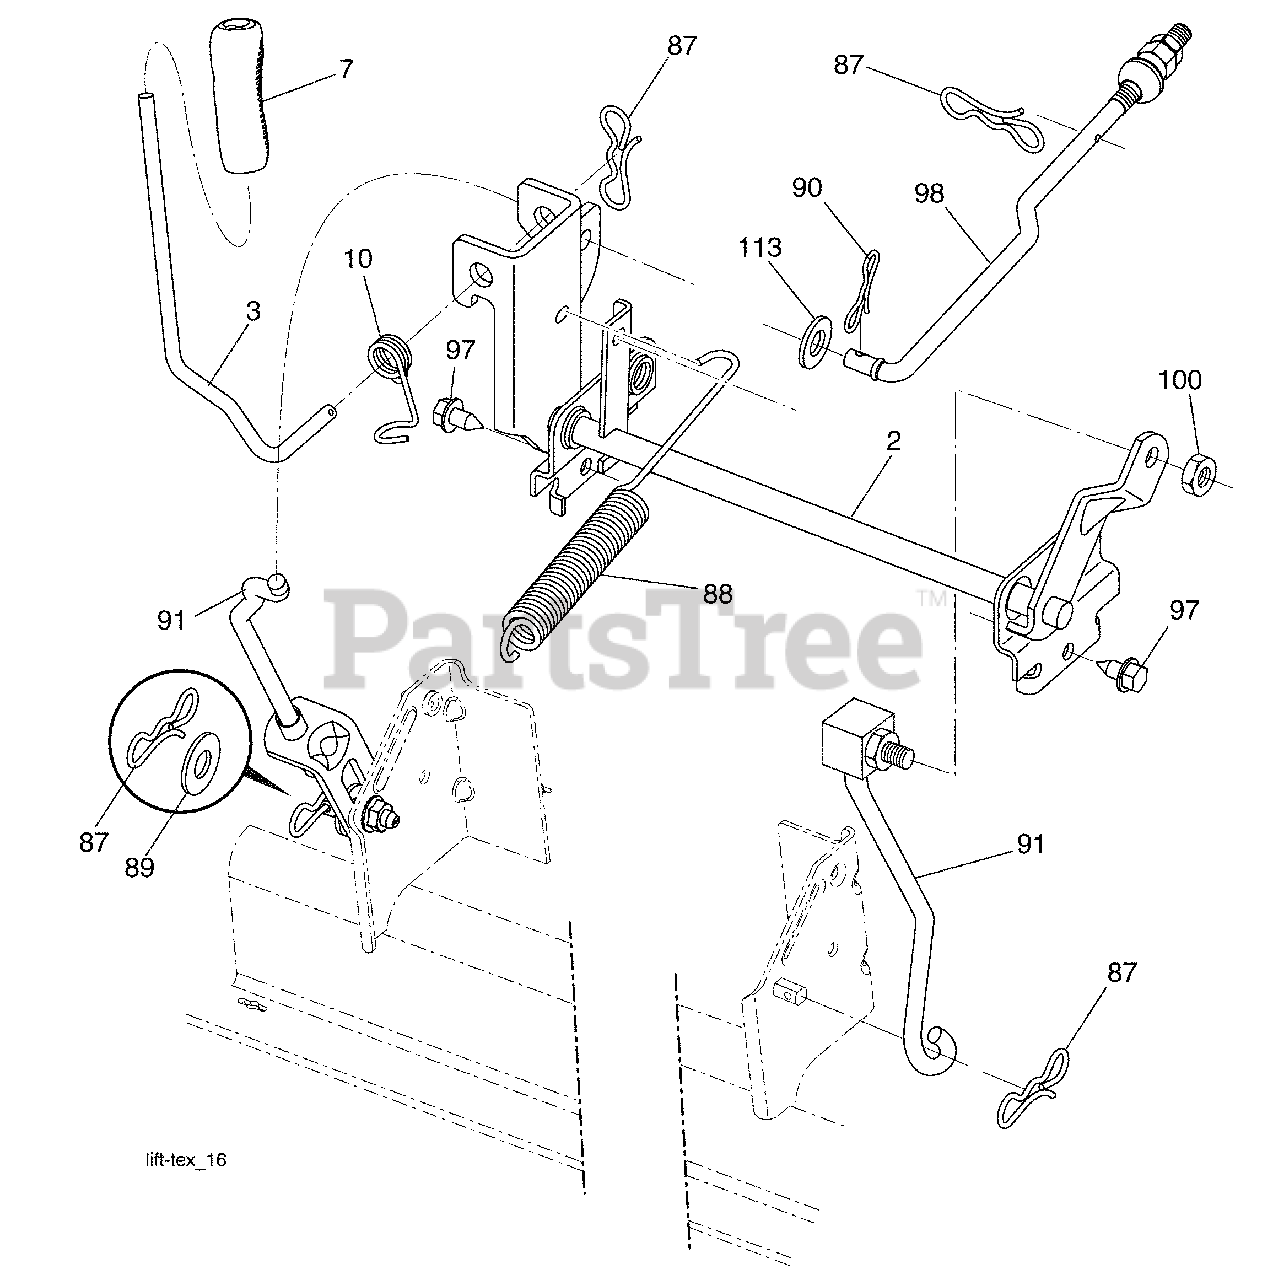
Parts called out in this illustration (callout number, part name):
2	Shaft Asm., Lift
3	Lever Lift Handle
7	Grip, Lever
10	Spring Torsion
87	Pin Cotter 7/16 Bow Tie Lock
88	Spring Lift Assist
89	Washer Clear Zinc
90	Pin Cotter 5/16 Bow Tie Lock
91	Link Lift Susp Mower Rear
97	Screw 3/8-16 x 3/4
98	Link Asm. Susp. Front Mower
100	Nut Centerlock 3/8-16 unc
113	Washer 17/32 x1-3/16 x 12 Ga.
